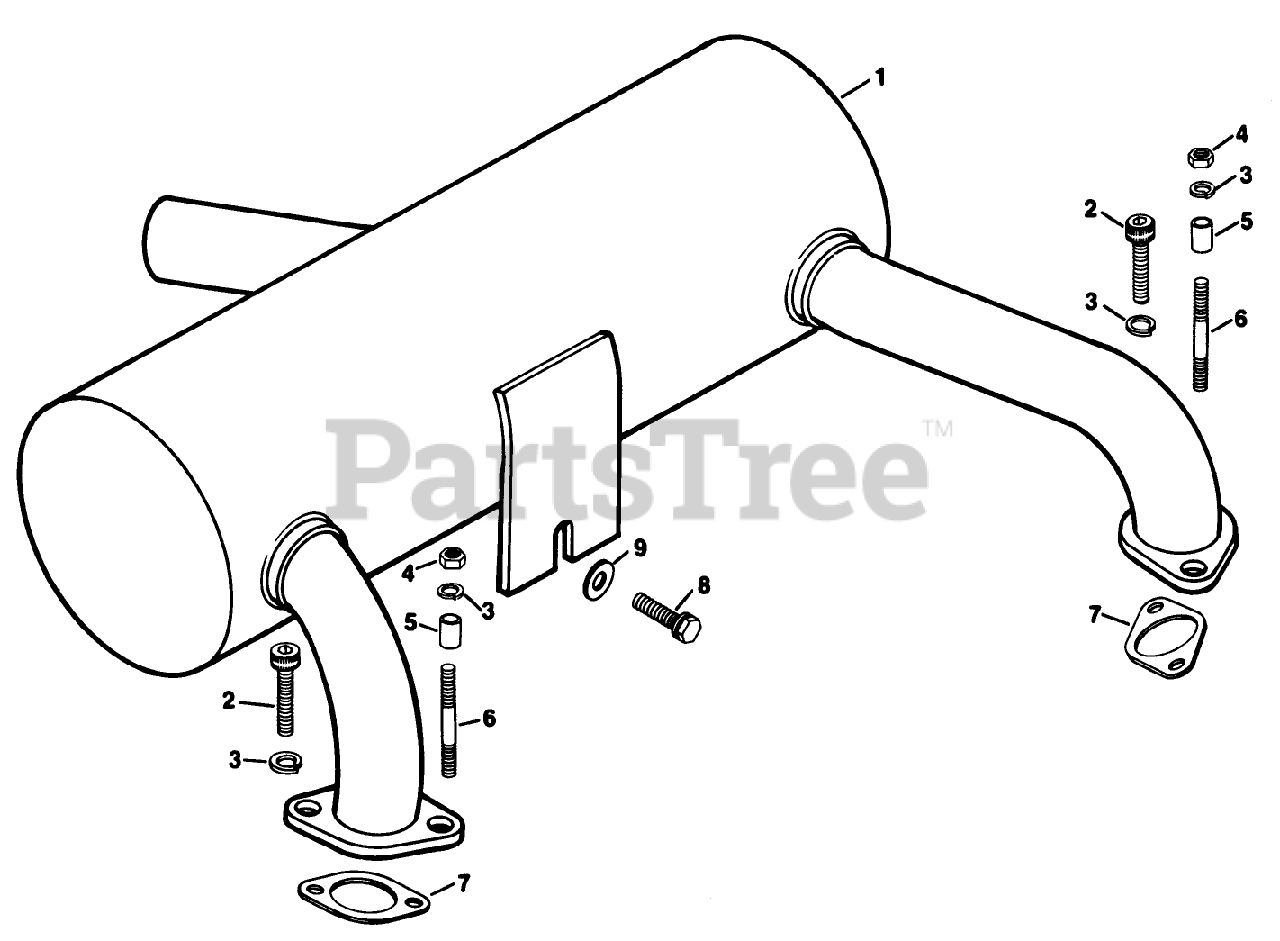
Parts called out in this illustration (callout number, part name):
1	Muffler
2	Screw
3	Washer
4	Nut
6	Stud
7	Gasket Exhaust
8	Screw
9	Washer
